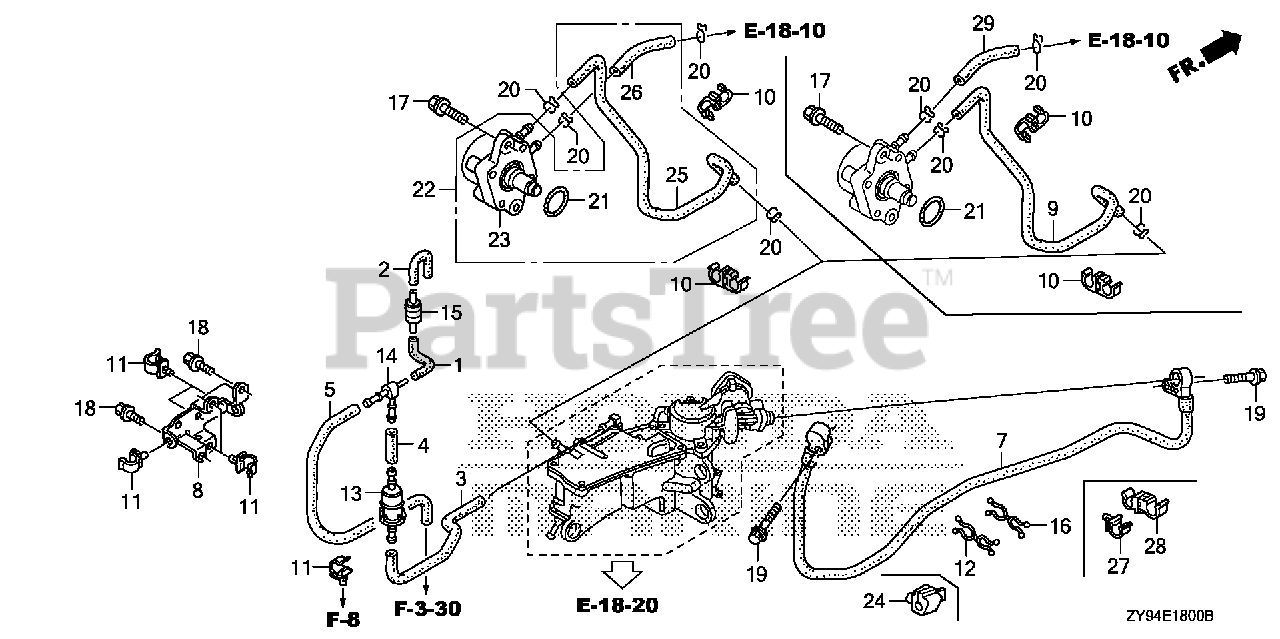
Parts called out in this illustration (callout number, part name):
1	TUBE A, CHECK VALVE
2	TUBE B, CHECK VALVE
3	TUBE A, AIR VENT
4	TUBE B, AIR VENT
5	TUBE C, AIR VENT
7	HOSE, FUEL
8	BRACKET, FUEL TUBE CLAMP
9	PUMP ASSY. KIT, FUEL (MSDS)
10	CLAMP A, FUEL TUBE
11	CLAMP B, FUEL TUBE
12	CLAMP C, FUEL TUBE
13	FILTER, FUEL
15	VALVE, CHECK
16	CLIP D, SPEEDOMETER CABLE
17	BOLT, FLANGE (6X22)
18	BOLT, FLANGE (6X14) (CT200)
19	BOLT, FLANGE (6X25)
20	CLIP, TUBE (B12)
21	O-RING (31.2X2.4)
22	PUMP ASSY. KIT, FUEL (MSDS)
23	PUMP ASSY., FUEL (MSDS)
24	GROMMET, FUEL HOSE
25	TUBE D, FUEL
26	TUBE E, FUEL
27	CLAMP B, FUEL TUBE
28	CLAMP, OXYGEN SENSOR
29	BULK HOSE, FUEL (7.5X8000) (7.3X160)
